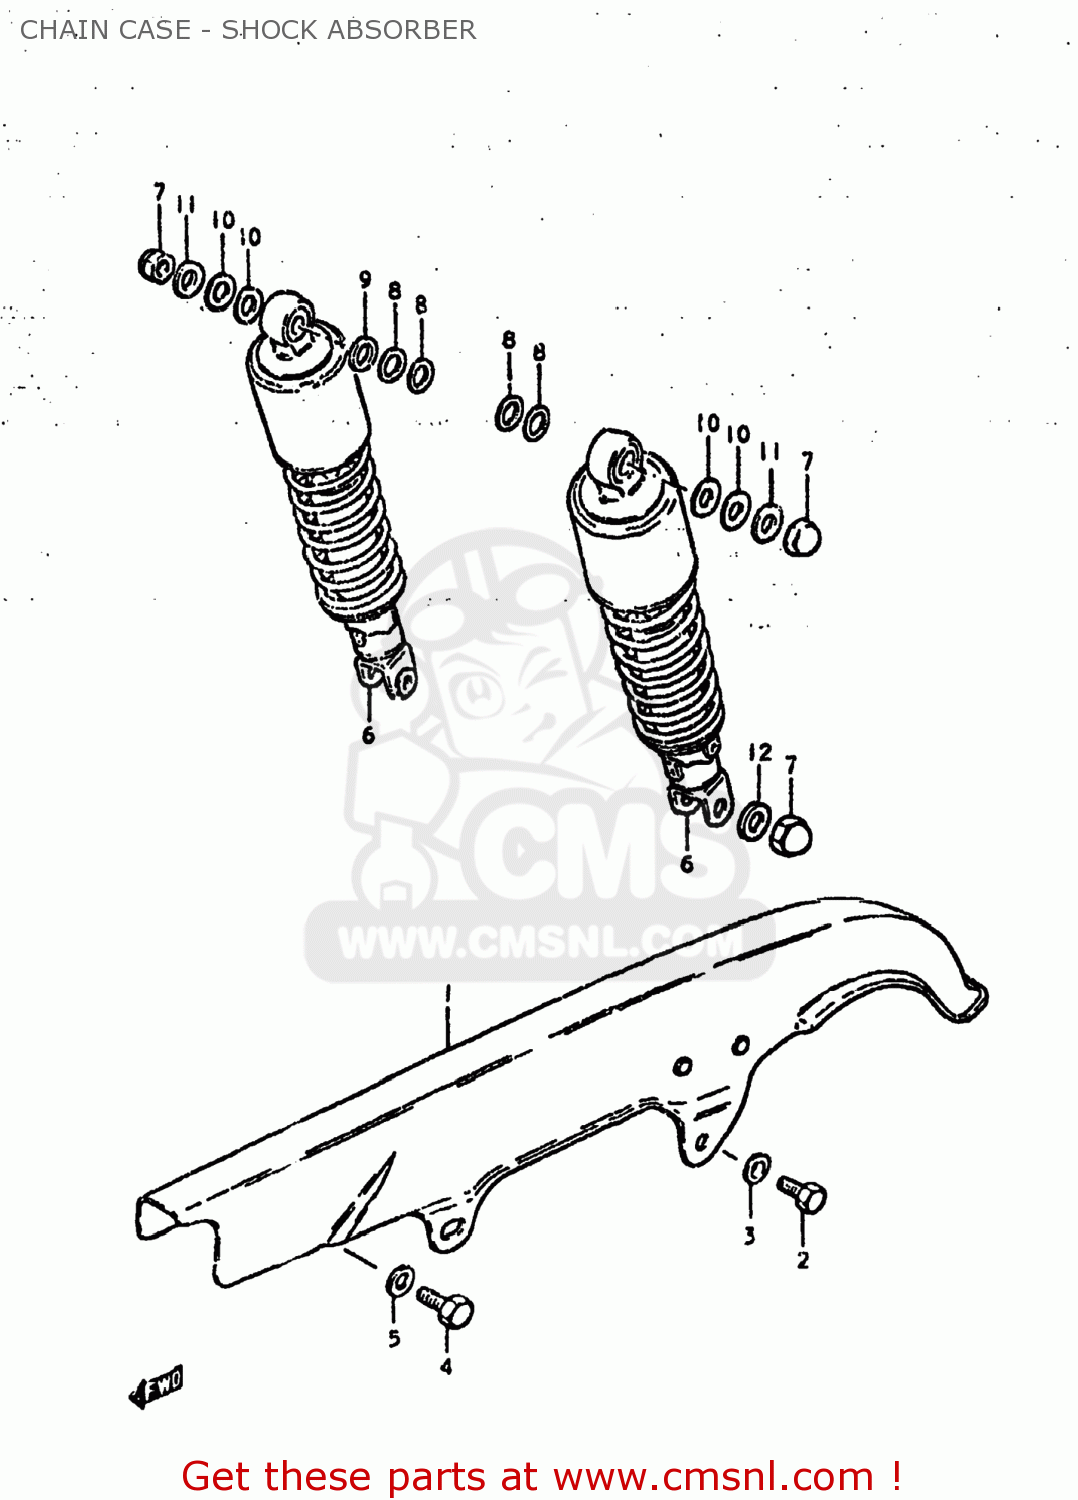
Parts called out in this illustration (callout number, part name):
1	CASE,CHAIN
2	BOLT 6X8
3	WASHER
4	BOLT
5	WASHER(6.5X18X1)
6	ABSORBER ASSEMBLY,REAR SHOCK
7	NUT, LOWER LH
8	WASHER
9	WASHER (12.5X24X3.2)
10	WASHER
11	WASHER(10.5X24X3.2)
12	WASHER (12.5X24X1.6)
